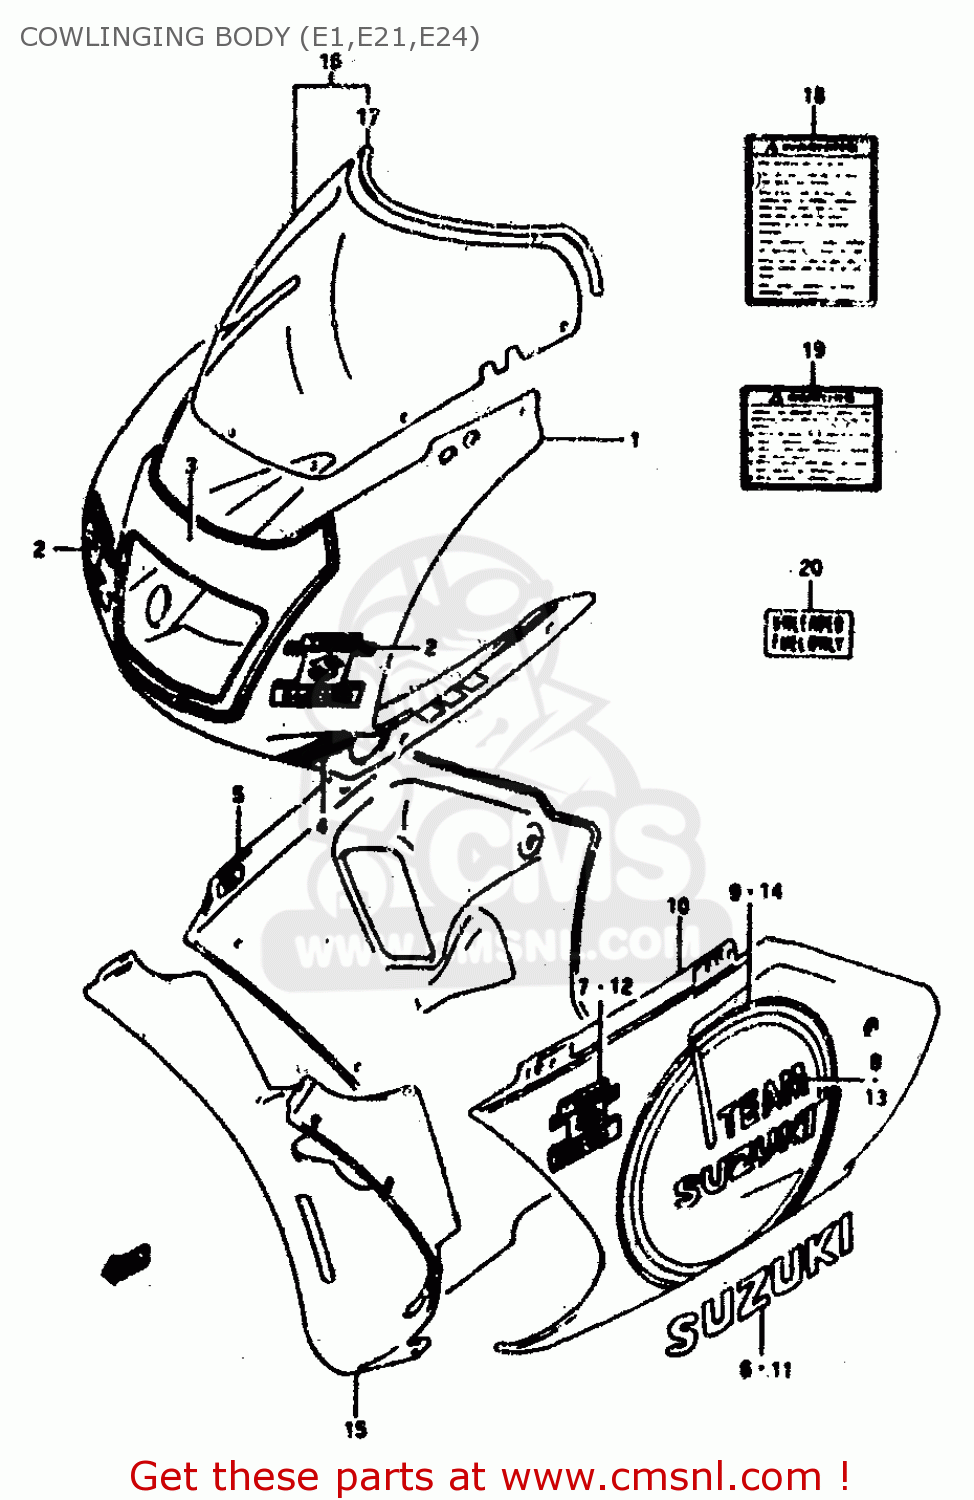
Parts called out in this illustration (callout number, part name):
1	COWLING ASSY, BODY (RED)
2	EMBLEM, 5
3	TAPE, UPPER
4	TATE SET, SIDE
5	COWLING ASSY, UNDER RH (RED/WHITE)
6	EMBLEM "SUZUKI"
7	EMBLEM, S
8	EMBLEM, RH,T-SUZUKI
9	TAPE, UNDER RH
10	COWLING ASSY, UNDER LH (RED/WHITE)
11	EMBLEM "SUZUKI"
12	EMBLEM, S
13	EMBLEM, LH,T-SUZUKI
14	TAPE, UNDER LH
15	COWLING, UNDER CENTER (WHITE)
16	SCREEN SET,WIND
17	MOLDING
18	LABEL (WARNING SCREEN)
19	LABEL
20	LABEL,FUEL CAUTION
